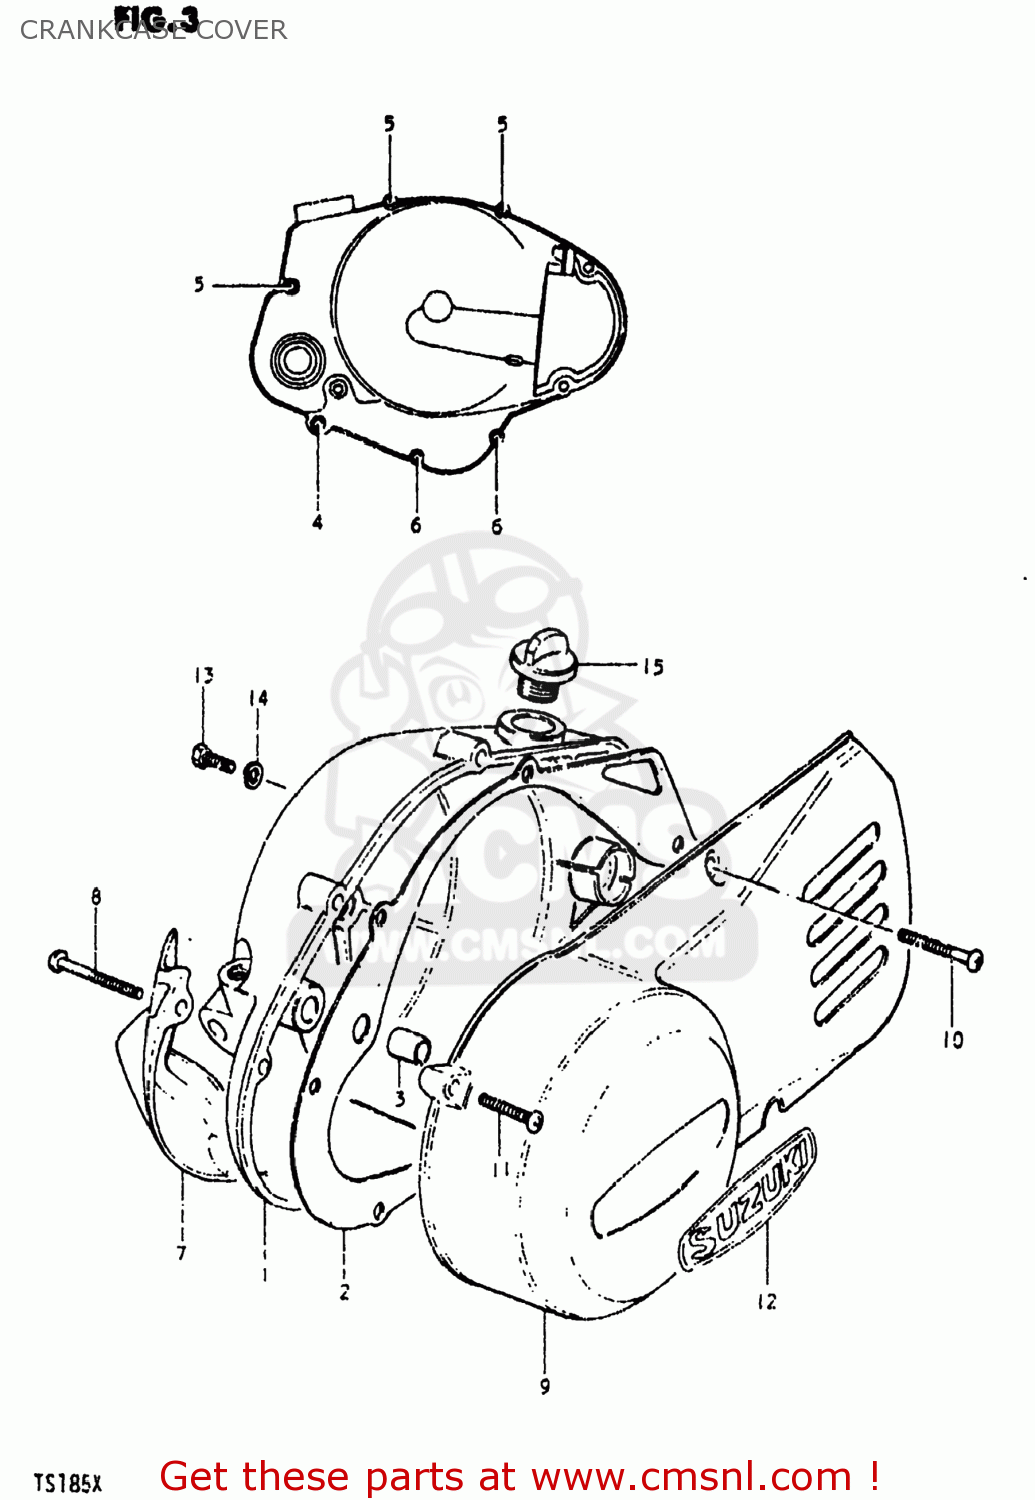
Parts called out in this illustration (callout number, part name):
1	COVER,CLUTCH
2	GASKET,CLUTCH COVER (MCA)
3	PIN
4	SCREW (6X45)
5	SCREW
6	SCREW
7	COVER,CLUTCH RELEASE A
8	SCREW
9	COVER,MAGNETO
10	SCREW 6X30
11	SCREW
12	EMBLEM,MAGNETO COVER
13	SCREW(6X10)
14	GASKET(6.2X11X1) (NAS)
15	PLUG
